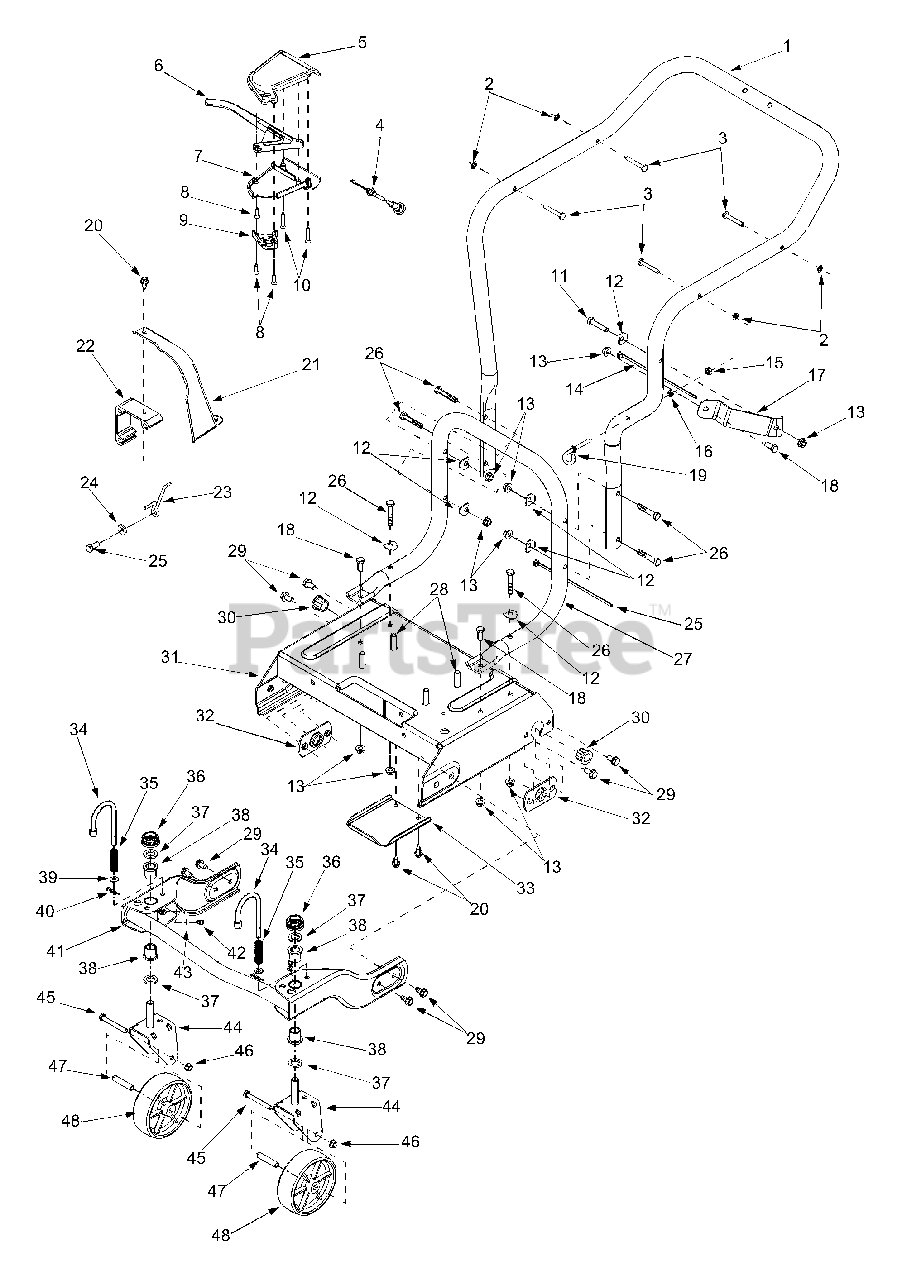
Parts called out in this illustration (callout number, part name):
2	Push Nut
3	Stud Pin .250 x 1.75
4	Clutch Cable 56"
5	Upper Clutch Cover
6	Drive Lever
7	Lower Clutch Cover
8	Screw #10-12 x .750
9	Mounting Cable Cap
10	Screw #10-16 x 1.25
11	Hex Cap Screw 5/16-18 x 1.50
12	Shoulder Washer .320 ID x .93 OD
13	Hex Flange Lock Nut 5/16-18
14	Cable Tie
15	Hex Nut 1/4-28
16	Lock Washer 1/4
18	Hex Cap Screw 5/16-18 x .75
19	Eye Bolt
20	Hex Washer Screw 1/4-14 x .625
21	Belt Cover
22	Engine Mounting Adapter
23	Belt Keeper
24	Flat Washer .344 x .75 x .12
25	Hex Cap Screw 5/16-24 x .75
26	Hex Cap Screw 5/16-18 x 1.75
28	Screw 3/8-16 x 1.25
29	Hex Washer Screw 5/16-18 x .625
30	Hex Flange Bearing .631 x .720
32	Axle Bracket
33	Transmission Cover
34	Lock Pin
35	Compression Spring
36	Push Cap
37	Flat Washer 5/8 ID x 1.0 OD
38	Flange Bearing .632 ID
39	Flat Washer .330 ID x .630 OD
40	Cotter Pin
42	Grease Fitting 3/16
43	Flat Washer.203 ID x .403 OD
45	Hex Cap Screw 3/8-16 x 3.0
46	Flange Lock Nut 3/8-16
47	Spacer
48	Wheel 6.0 x 2.0
